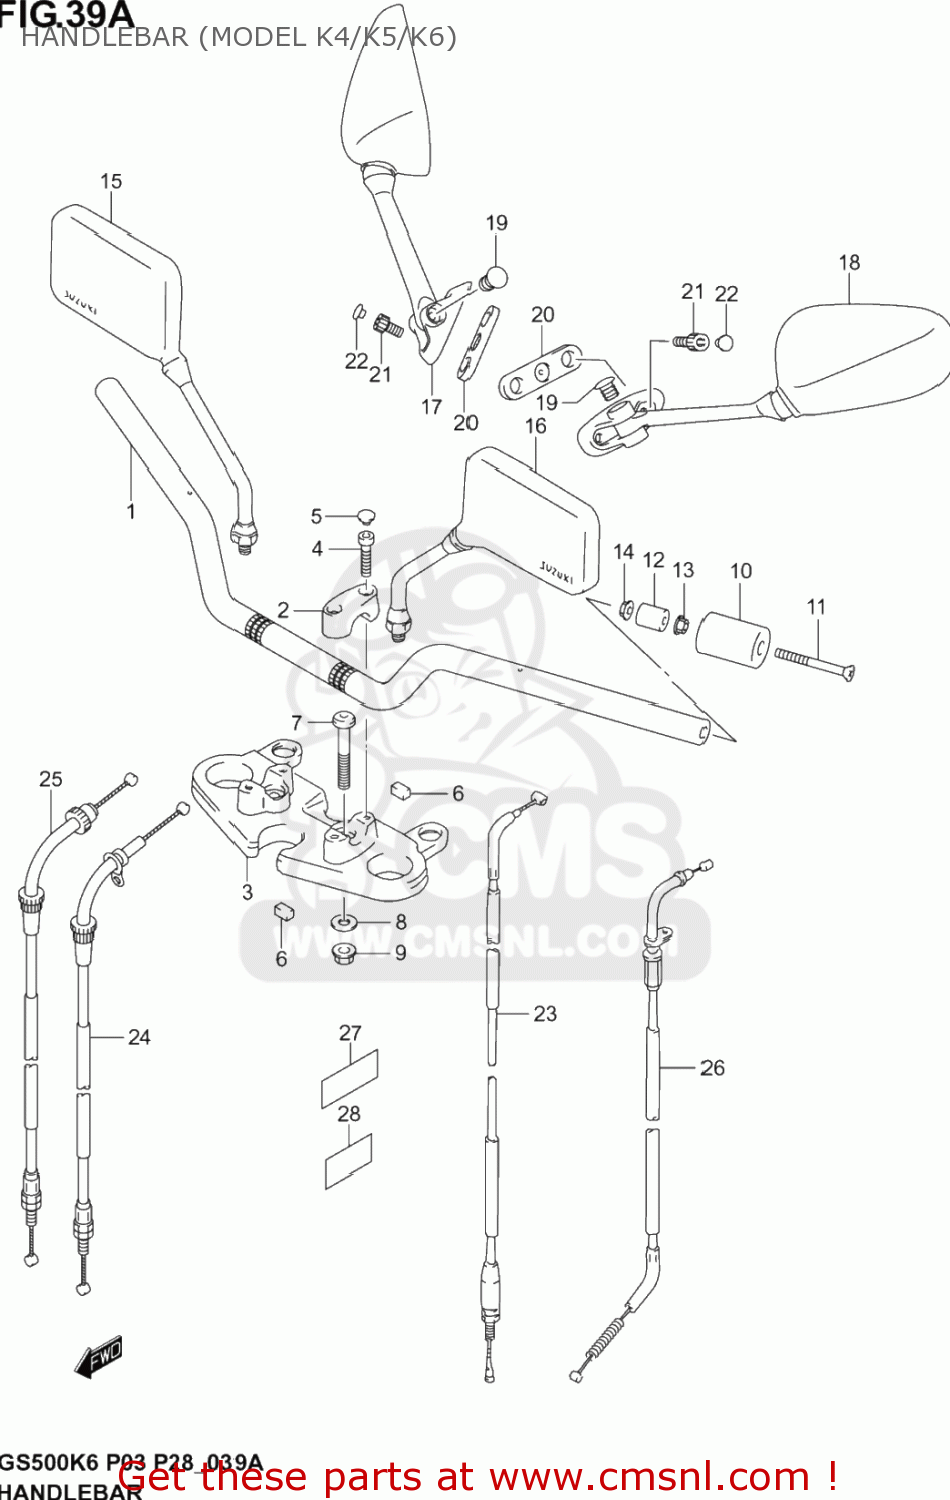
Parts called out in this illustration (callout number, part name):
1	HANDLEBAR
2	HOLDER,UPPER
3	HOLDER, LOWER
4	BOLT
5	CAP(OD:11)
6	CUSHION,HANDLE HOLDER
7	BOLT
8	WASHER
9	NUT
10	BALANCER,HANDLEBAR
11	SCREW,HANDLE B
12	EXPANDER,HANDLE BALANCER
13	NUT
14	NUT
15	MIRROR ASSEMBLY,REAR VIEW
16	MIRROR ASSEMBLY,REAR VIEW
17	MIRROR ASSY,RR VIEW,R
18	MIRROR ASSY,RR VIEW,L
19	CAP(OD:14)
20	CUSHION,RR VIEW MIRRORR
21	BOLT
22	CAP(OD:10)
23	CABLE ASSY,CLUTCH
24	CABLE ASSY,THROTTLE NO.1
25	CABLE ASSY,THROTTLE NO.2
26	CABLE,STARTER
27	PROTECTOR, CABLE
28	PROTECTOR, CABLE
